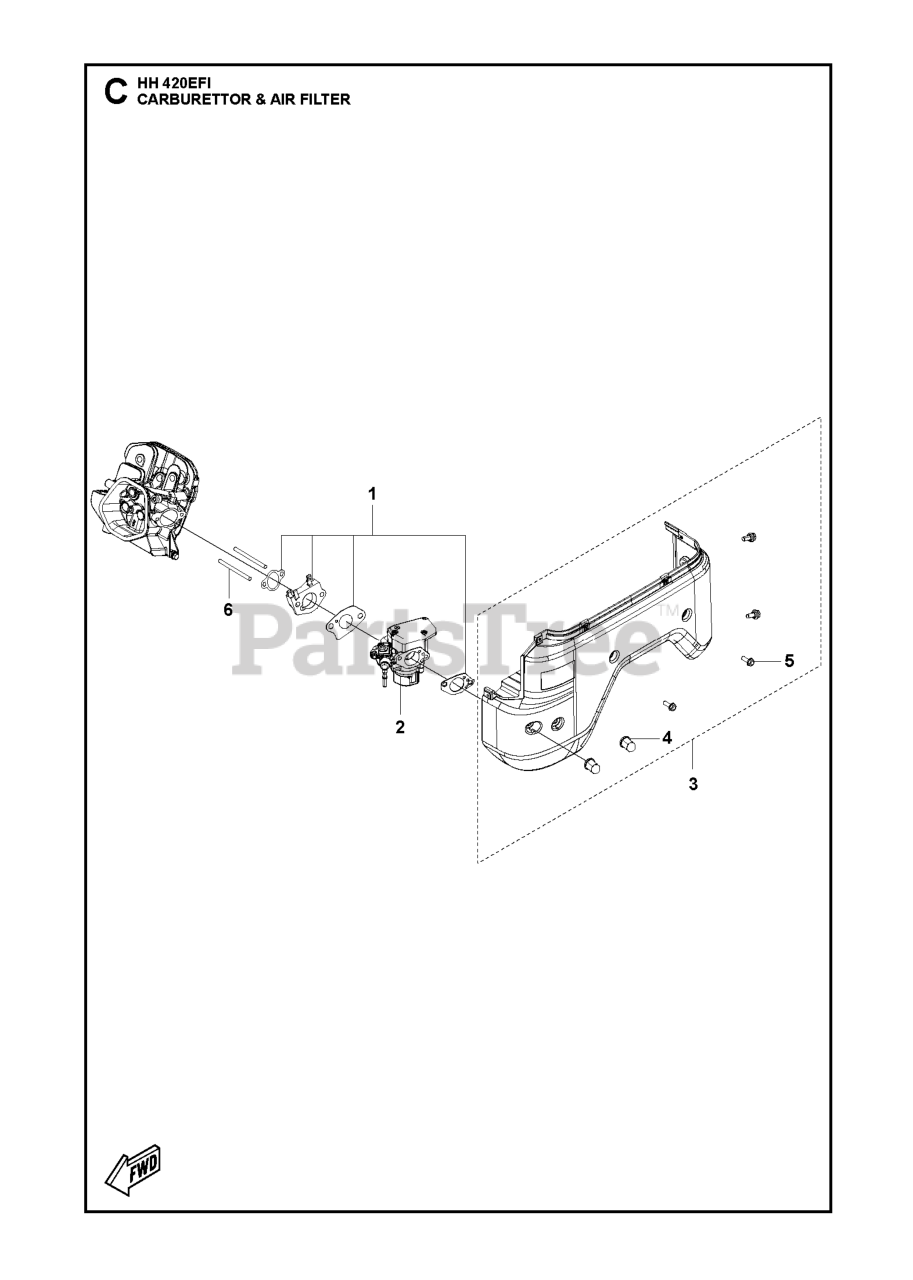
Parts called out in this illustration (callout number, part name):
1	GASKET KIT CARBURETTOR GASKET
2	ELECTRIC MODULE ECU
3	AIR FILTER ASSY
5	BOLT
